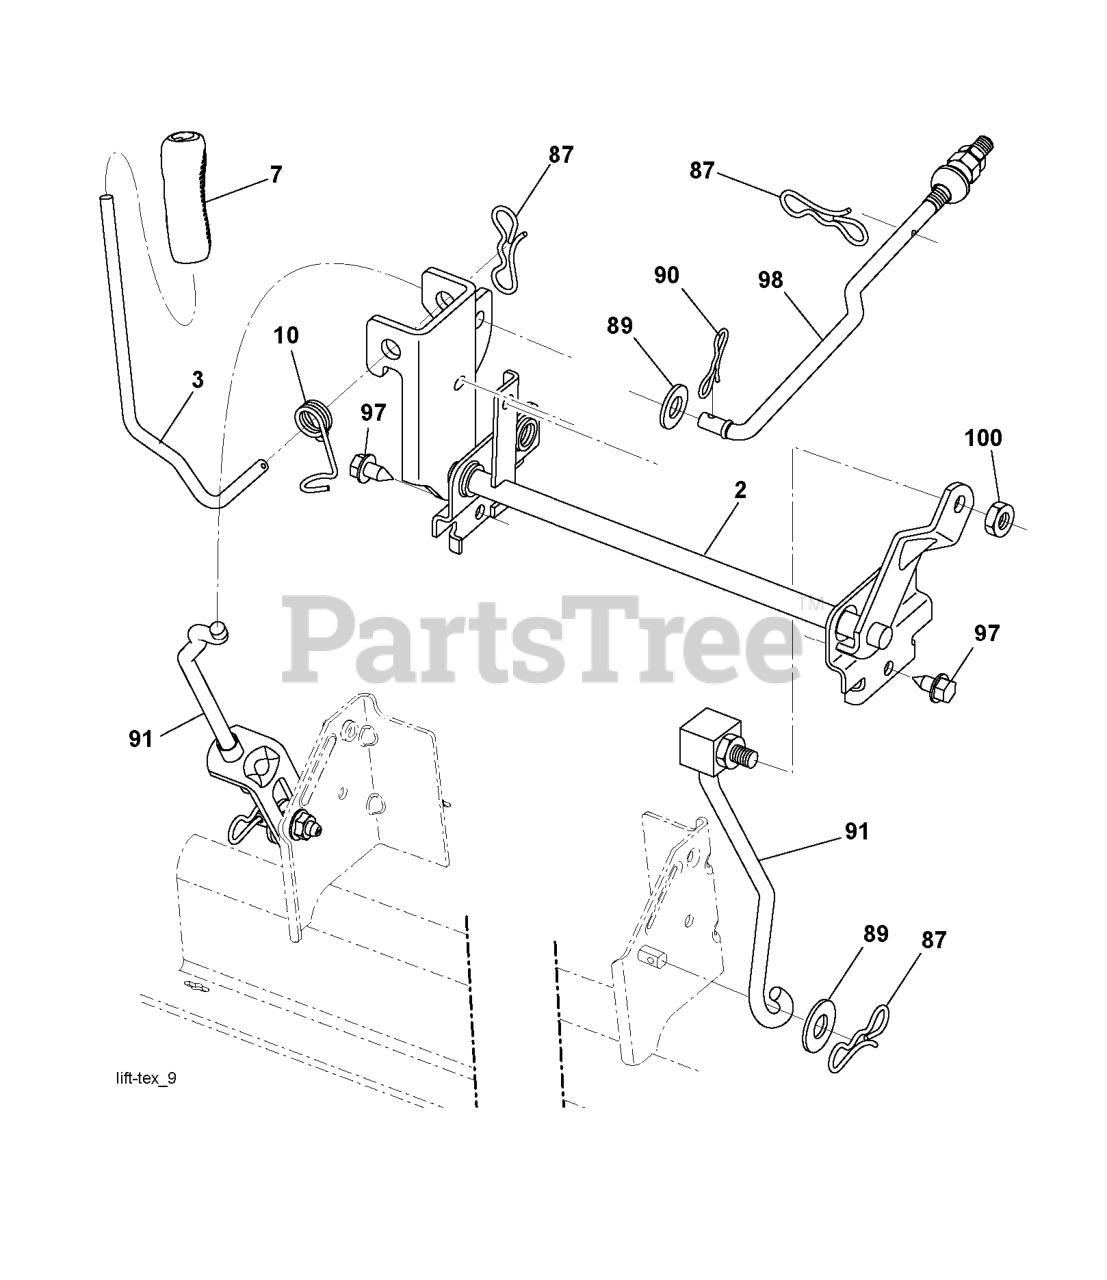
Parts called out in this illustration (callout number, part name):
2	SHAFT.ASM.LIFT.CROSS.H
3	LEVER.LIFT.HANDLE.LT
7	GRIP.LEVER.5625.ID
10	SPRING.TORSION.LIFT.HANDLE
87	PIN.COTTER.7/16.BOW TI.
89	WASHER.CLEAR.ZINC
90	PIN.COTTER.5/16.BOW TI
91	LIFT LINK SUSP. MOWER REAR
97	SCREW 3/8-16X3/4
98	LINK.ASM.SUSP.FRONT.MW
100	LOCKNUT
